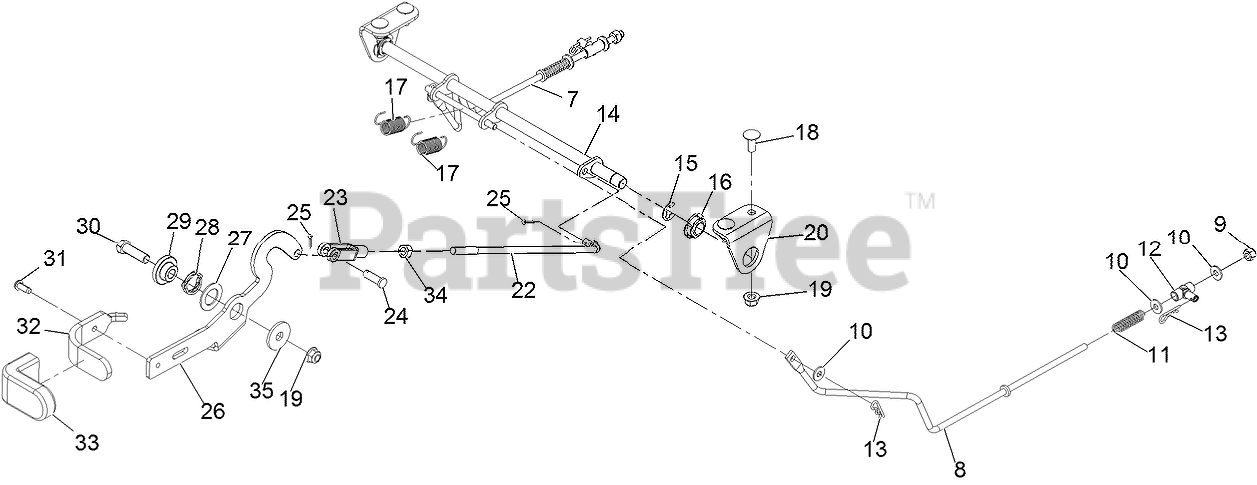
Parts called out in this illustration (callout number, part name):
7	ROD-BRAKE, RH
8	ROD-BRAKE, LH
9	NUT-LOCK, NI
11	SPRING-COMPRESSION
12	MOUNT-PIVOT
14	PIVOT-BRAKE
15	RING-RETAINING, EXTERNAL
16	BEARING-SPHERICAL
17	SPRING-EXTENSION
18	SCREW-CARR
19	NUT-HF, NI
20	ANGLE-MOUNT PIVOT
22	ROD-LINK HANDLE
23	YOKE-ADJUSTABLE
24	PIN-CLEVIS
25	PIN-COTTER
26	LEVER-BRAKE
27	WASHER-THRUST
28	WASHER-WAVE
29	PIVOT-FLANGE
30	SCREW-HH
32	HANDLE-BRAKE
33	GRIP-LEVER
34	NUT-HEX
35	WASHER
